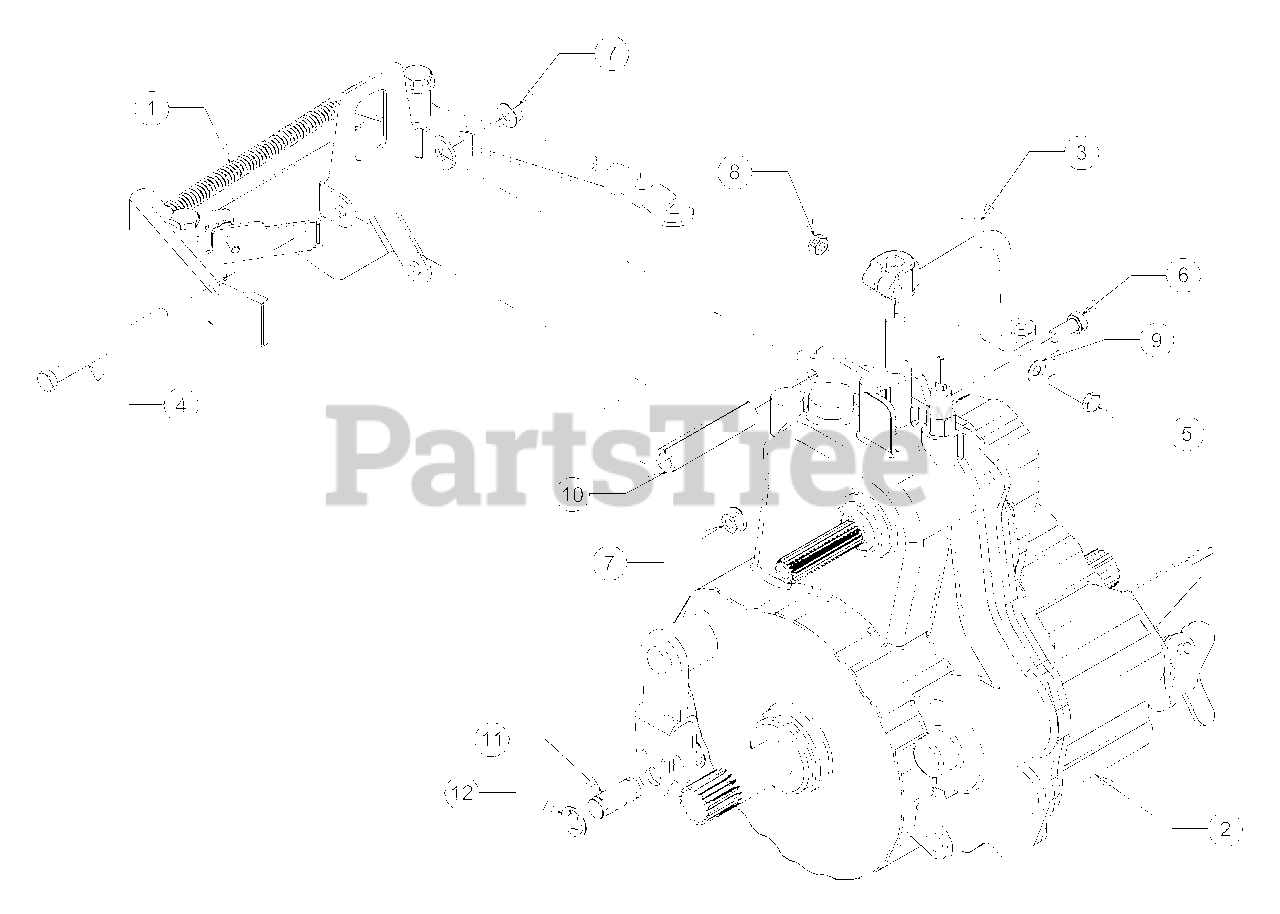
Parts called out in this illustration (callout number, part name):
1	Shift Assembly, Interlock
2	Transmission,Tuff Torq Model KT 35
3	Lever, Transmission
4	Hex Screw, 3/8-16 x 4.50, Gr5
5	Hex Screw, 5/16-18 x 1.50, Gr5
6	Hex Screw, 3/8-16 x .880, Gr5
7	Lock Nut, Hex Flange 3/8-16
8	Nut, Hex Lock, 5/16-18
9	Washer, Flat, .330 x .687 x .030
10	Spacer, .505 x .75 x 3.31
11	Pin, .625 x 1.37
12	E-Ring, .625
